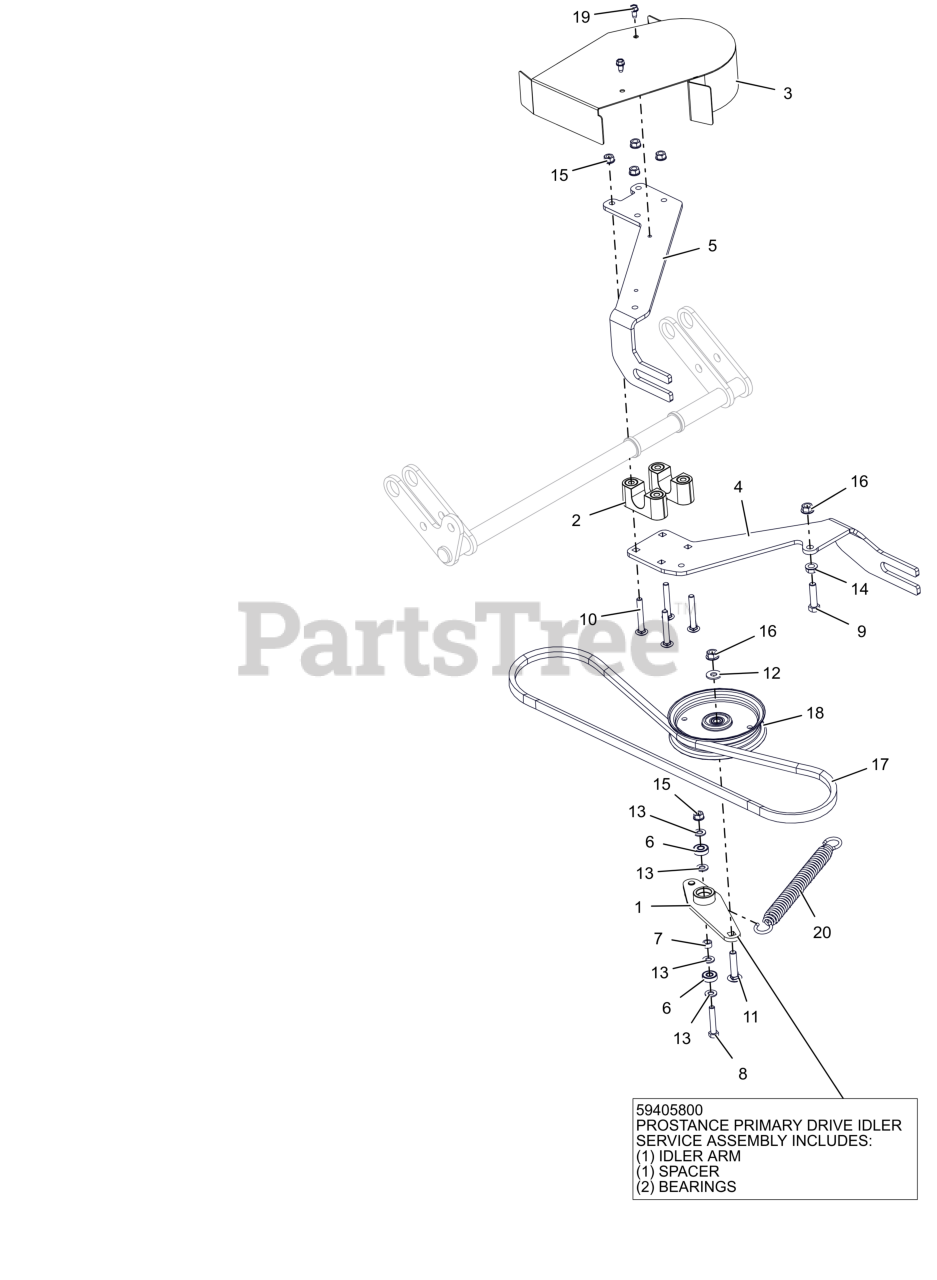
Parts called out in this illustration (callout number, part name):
1	WLDMT, IDLER ARM
1	PROSTANCE PRIMARY DRIVE IDLER ASSEMBLY
2	ASM-BUSHING, DECK LIFT
3	WLDMT, TOP IDLER GUARD
4	BRKT, PIVOTING IDLER (BLACK)
5	BRKT, UPPER PIVOTING IDLER (BLACK)
6	BRG-BALL .315X.866X.276(608)
7	SPACER, .329/.334 X .500/.505 X .283
8	BLT, HEX .31-18X1.75 G5 ZCC
9	BLT, HEX .38-16X1.50 G5 ZCC
10	BLT, RHSSN.31-18X2.25 G5 ZCC
11	BLT, RHSSN .38-16X1.75 G5 ZCC
12	WSHR,FLT .375X.875X.083 ZCC
13	WSHR, HRDN 0.344X0.688X0.065
14	NUT, SPNLK-FLG .38-16 G5 ZCC
15	NUT,LK-CTR-FLG .31-18 GF ZCC
16	NUT-LK-CTR-FLG .375-16 GF ZCC
17	V-BELT, 5L RAW EDGE EPDM
18	IDLER- FLAT - 5.00" X .75"
19	SCR-TAP .25-20X.50 HWH ZCC
20	SPRING- EXTENSION
